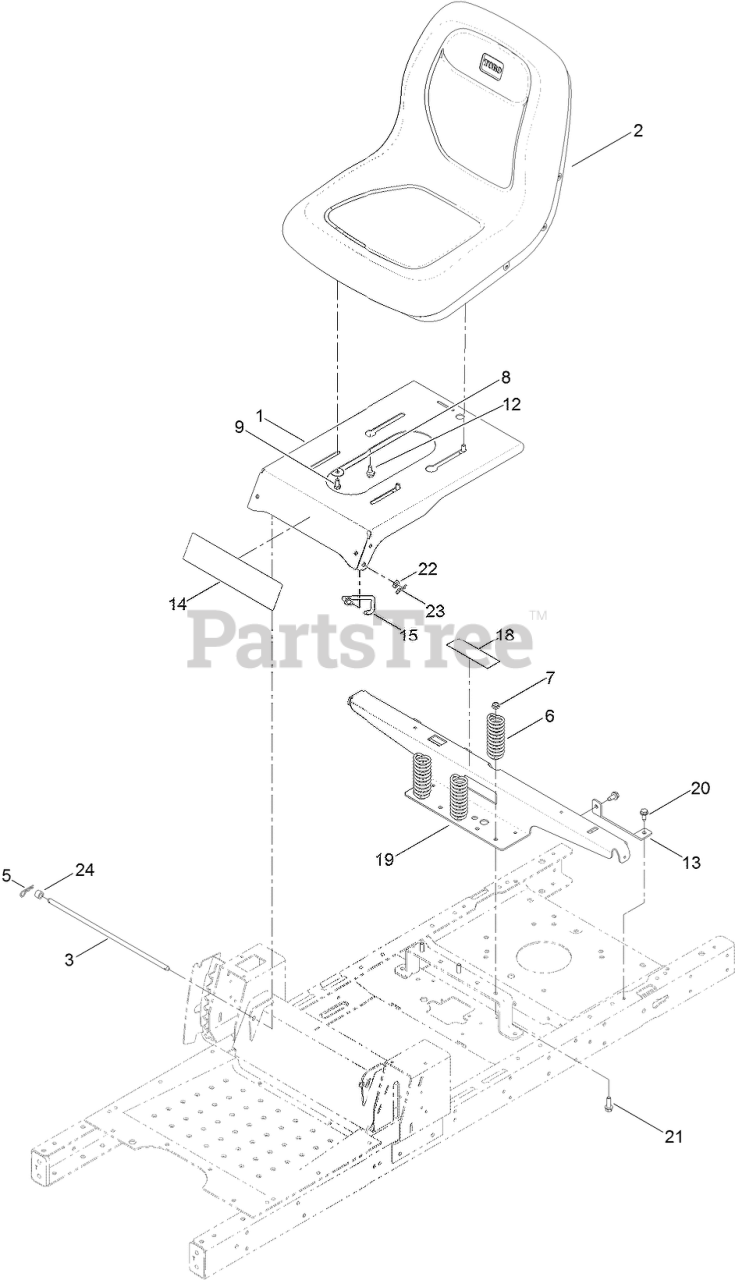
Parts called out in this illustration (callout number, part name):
1	PAN-SEAT
2	SEAT-18 INCH
3	ROD-STOP
5	PIN-COTTER
6	SPRING-COMPRESSION
7	NUT-HF, NI
8	WASHER-PIVOT
9	SCREW-HH
12	BOLT-SHOULDER
13	SUPPORT-TANK, REAR
14	DECAL-TIMECUTTER
15	STOP-SEAT
18	DECAL-SERVICE, CE
19	SUPPORT-POD, WIDE
20	SCREW-HWHTF
21	SCREW-HHF
22	WASHER-PLAIN
23	PIN-COTTER
24	BUSHING-LEVER, LIFT
